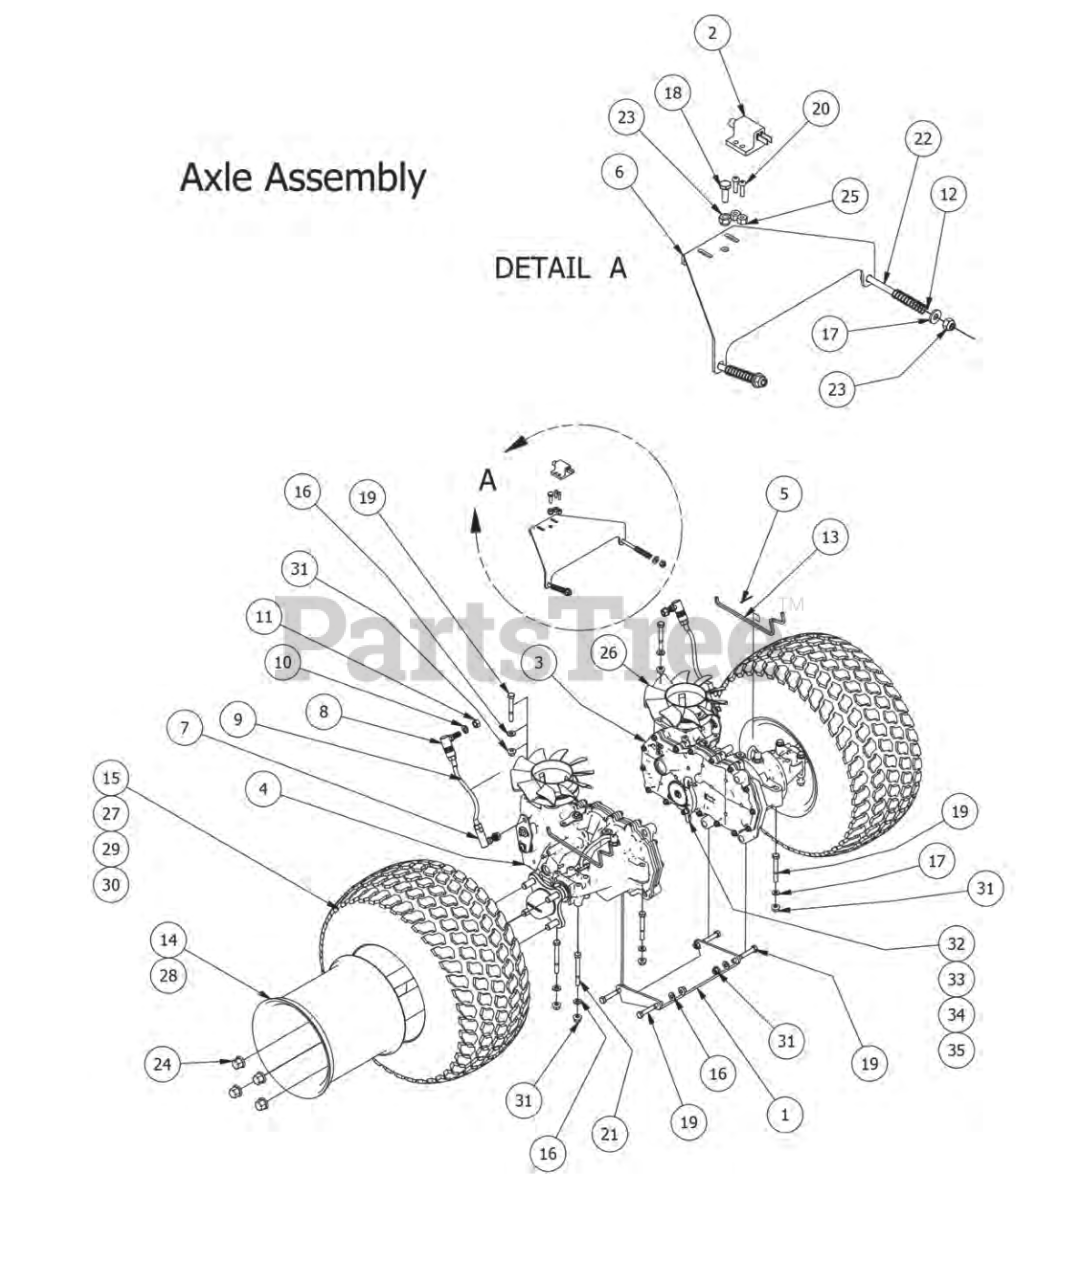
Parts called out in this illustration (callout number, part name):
1	MZ Transaxle Support (Lower)
2	Safety Switch
3	EZT Right MZ Models
4	EZT-Left MZ Models
5	Cotter Pin-Brake bar on Mz
6	MZ Brake Lock Bracket
7	3/8-24 Ball Joint
8	Quick Release Ball Joint
9	MZ/Magnum Push Rod - 2014
10	3/8" Lock Washer
11	3/8" Fine Threaded Jam Nut
12	Brake Spring
13	MZ Brake Release Bar
14	Rear rim for a 48 & 54"
15	18 x 9.50-8 Tire Only MZ 48 &54" Deck only
16	5/16" Flat Washer
17	1/4" Flat Washer
18	1/4" x 3/4" Hex Bolt
19	5/16" x 2 1/2" Bolt
20	10-24 X 5/8 BS C/S 18-8 SS
21	5/16" x 3" Hex Bolt
22	1/4-20 x2-1/2 Gr2 hex C/s zinc
23	1/4" Nylock Nut
24	Acorn Lug Nut
25	10-24 Nylon Insert Locknut
26	MZ Fan & Pulley Kit
27	42" MZ 18x 7.50-8 tire only
28	Rear rim only 42" MZ
29	18x9.50-8 48 & 54" Deck Tire and Wheel Assembly
30	18x8.50-8/8" 42" Deck Tire and Wheel Assembly
31	5/16" Nylon Flange Nut
32	MZ Brake Cog Kit
33	MZ Retainer Ring for Brake
34	MZ Brake Gear
35	MZ Brake Arm Kit
